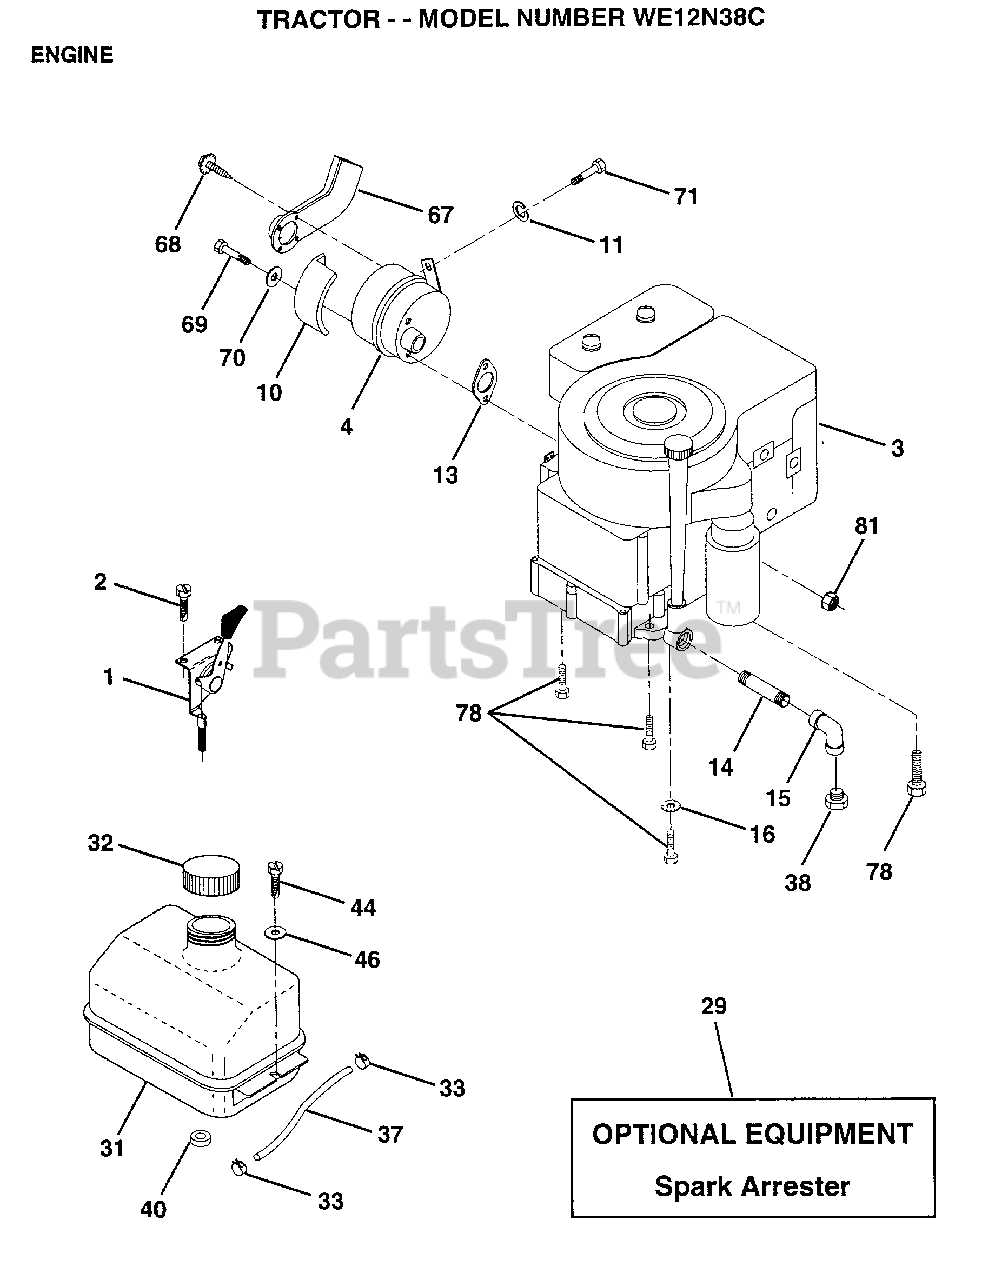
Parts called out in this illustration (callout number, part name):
1	THROTTLE CONTROL
2	SCREW LT
3	ENG B&S 10-12.5HP PWRBLT DC
4	MUFFLER LTV
10	SHIELD HEAT LTV
13	GASKET ENG 1 313 LD TIN PLATED
14	PIPE NIPPLE
15	ELBOW
16	LOCKWASHER
31	TANK.FUEL.LT.
32	CAP ASM FUEL
33	HOSE CLAMP
37	LINE FUEL
44	SCREW HEX CRT
46	WASHER
67	DEFLECTOR MUFFLER
69	"BOLT,HEX"
70	WASHER T
78	SCREW
81	NUT
